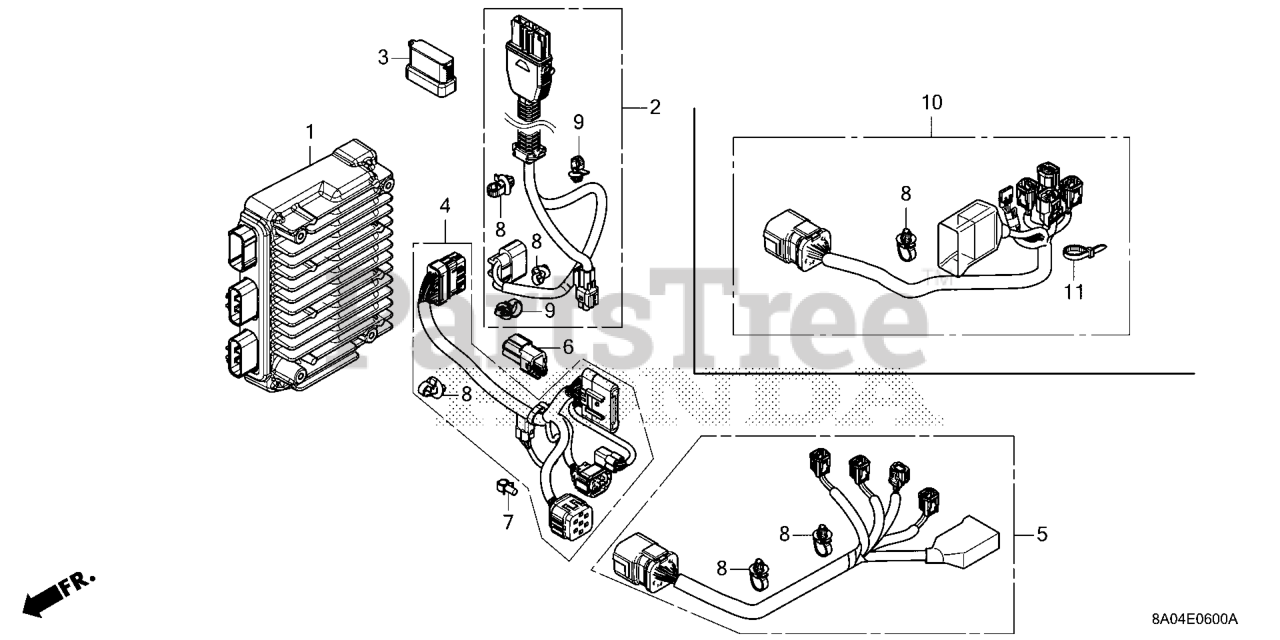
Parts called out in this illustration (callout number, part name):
2	CABLE ASSY., POWER
4	HARN, MAIN WIRE
6	CONNECTOR, DUMMY (4P)
7	CLIP, BRAKE PIPE (A) (FOR NEUTRAL SWITCH)
8	CLIP, HARNESS BAND (145MM) (BLACK)
9	CLIP, HARNESS BAND (164.5MM) (DARK BLUE)
10	HARN, CONTL WIRE
11	BAND, WIRE HARNESS (172MM) (BLACK)
